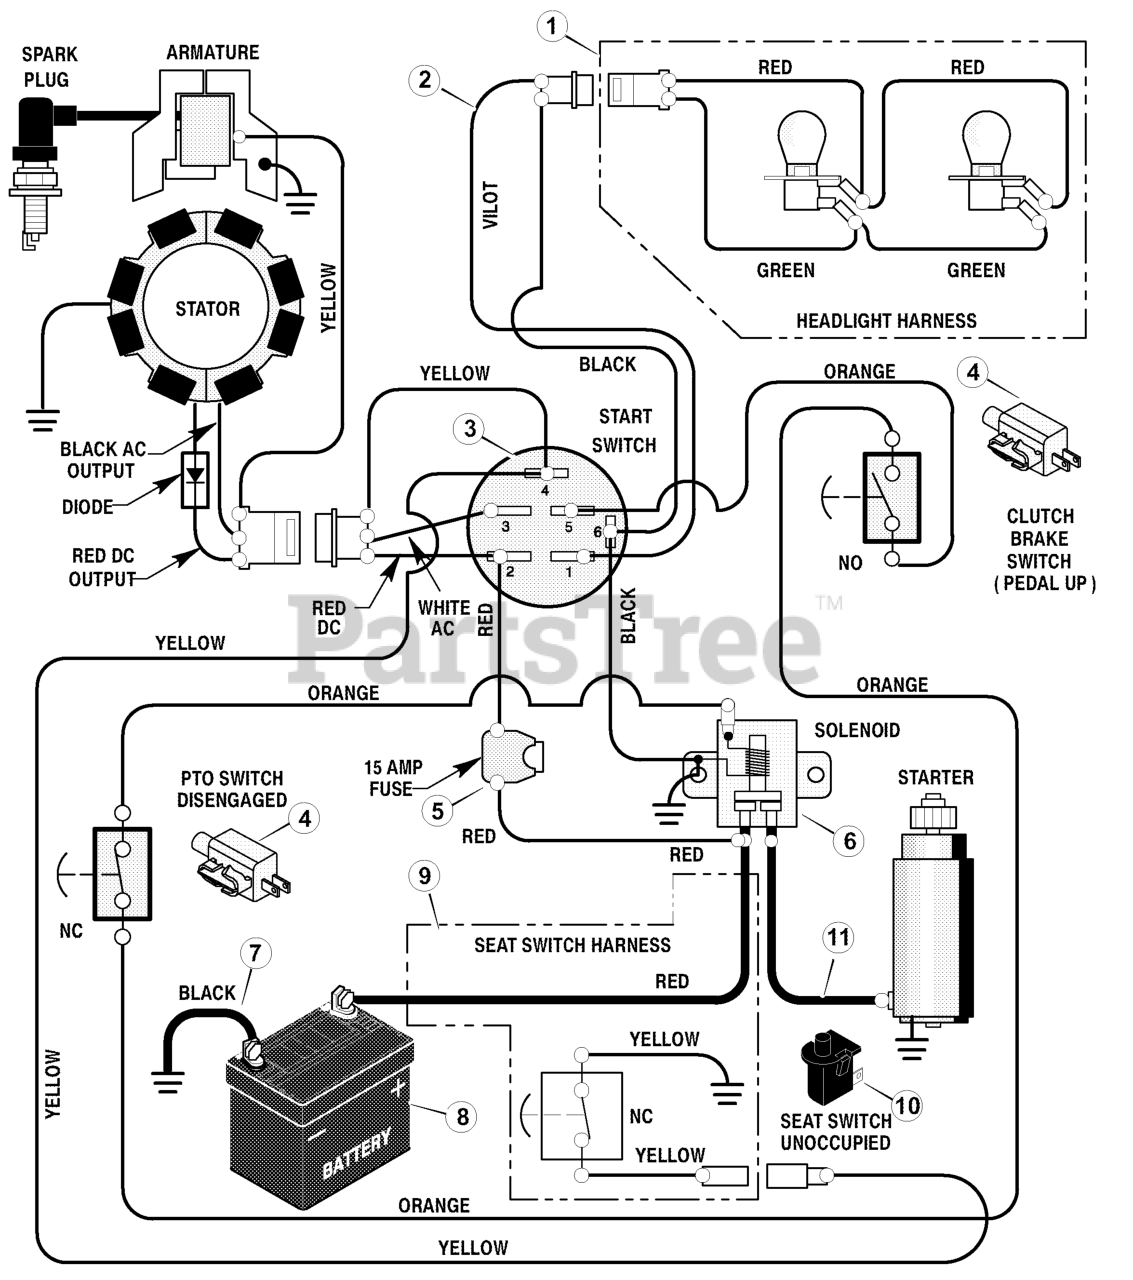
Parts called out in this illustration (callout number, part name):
1	Harness, Light Wire
2	Harness, Chassis Wire
3	Switch, Ignition
4	Switch, Limit
6	Solenoid
7	Cable, Battery Ground
9	Harness, Seat Switch Wire
10	Switch, Seat Sensor
